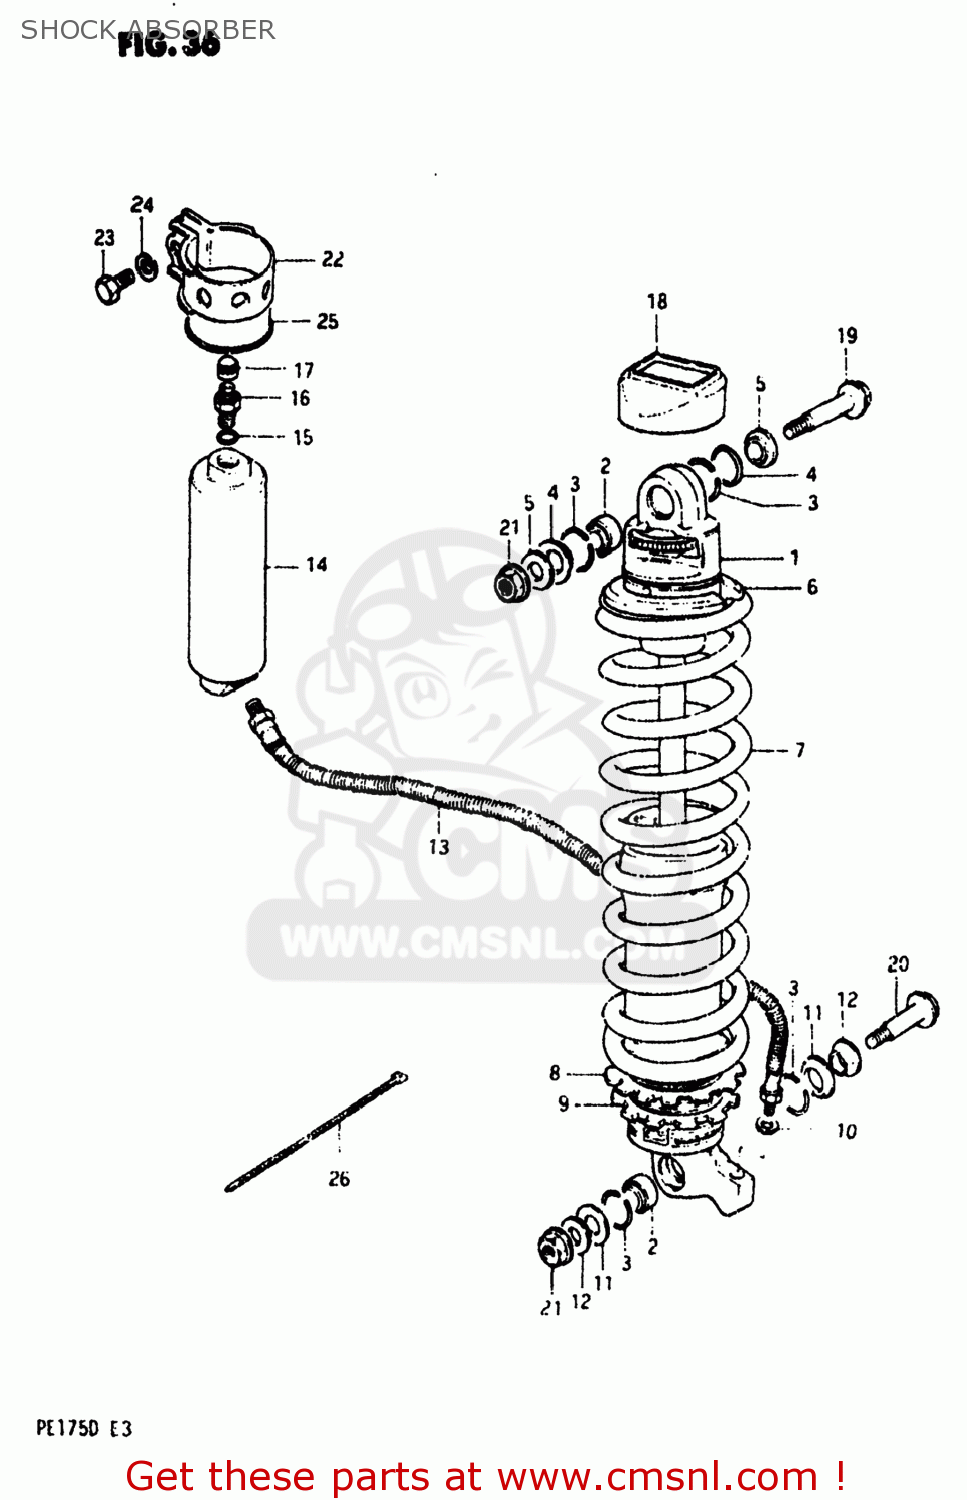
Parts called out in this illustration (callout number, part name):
1	ABSORBER ASSEMBLY,REAR SHOCK
2	SPHERICAL BEARING,REAR C
3	RING,STOP
4	O-RING,FORK INNER TUBE
5	SPACER,REAR SHOCK,UPPER
6	SPRING GUIDE
7	SPRING
8	GUIDE,SPRING
9	GUIDE,REAR SHOCK ABSORBER SPRING
10	O-RING,RESERVE TANK
11	DUST SEAL,REAR SHOCK
12	SPACER,REAR SHOCK,UPPER
13	HOSE,REAR SHOCK ABSORBER
14	RESERVE TANK,REAR SHOCK
15	O-RING
16	VALVE ASSEMBLY,REAR CUSHION
17	CAP,FRONT FORK AIR VALVE
18	CAP
19	BOLT(10X70)
20	BOLT(10X54)
21	NUT
22	BRACKET
23	BOLT
24	LOCK WASHER
25	CUSHION,RESERVOIR TANK
26	CLAMP
